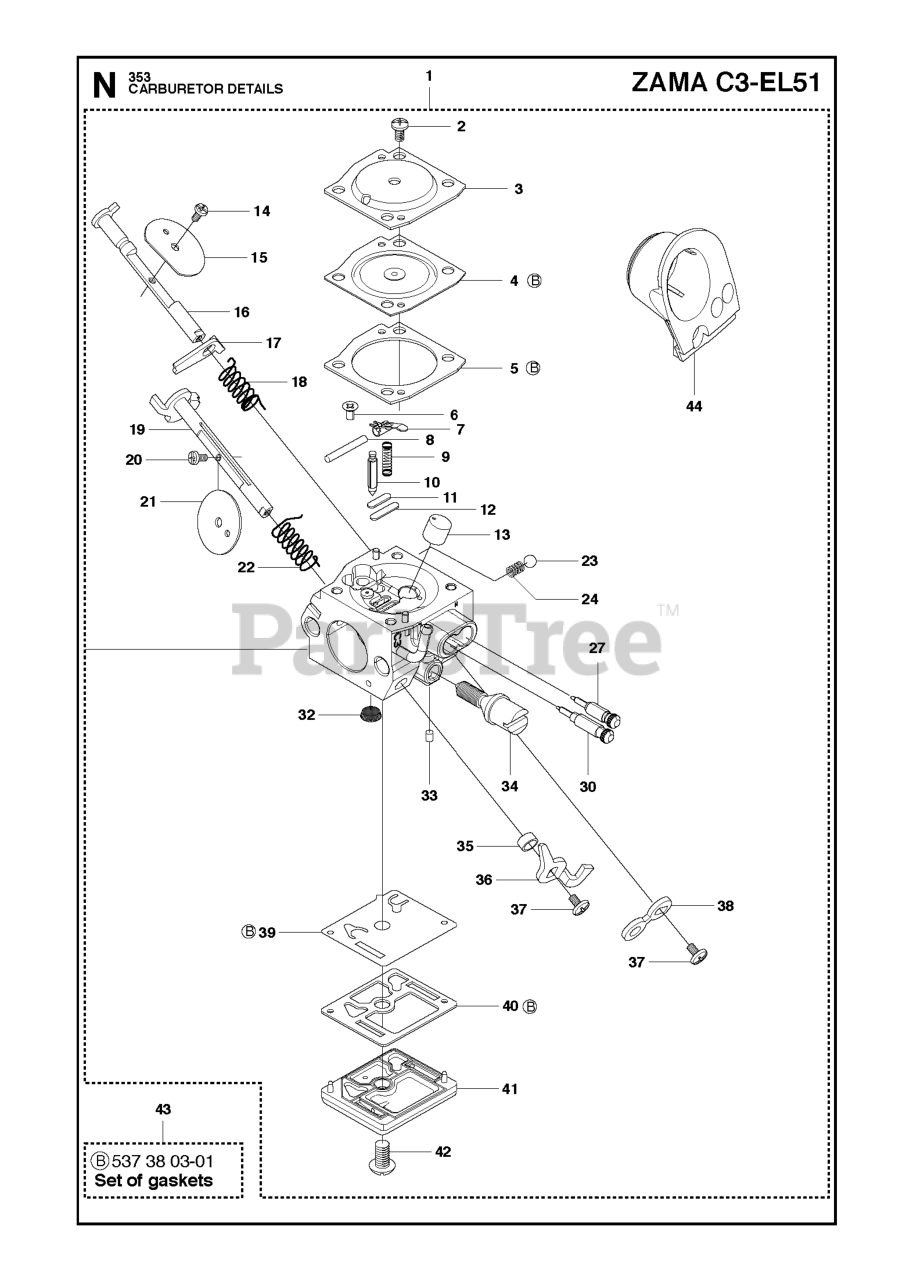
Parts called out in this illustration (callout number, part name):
1	CARBURETOR
8	PIN RETAINING SCREW
15	CHOKE FLAP
16	CHOKE SHAFT
17	THROTTLE LOCK
19	THROTTLE SHAFT
21	THROTTLE FLAP
30	LOW SPEED NEEDLE
34	IDLE SCREW
39	PUMP DIAPHRAGM
43	GASKET SET
